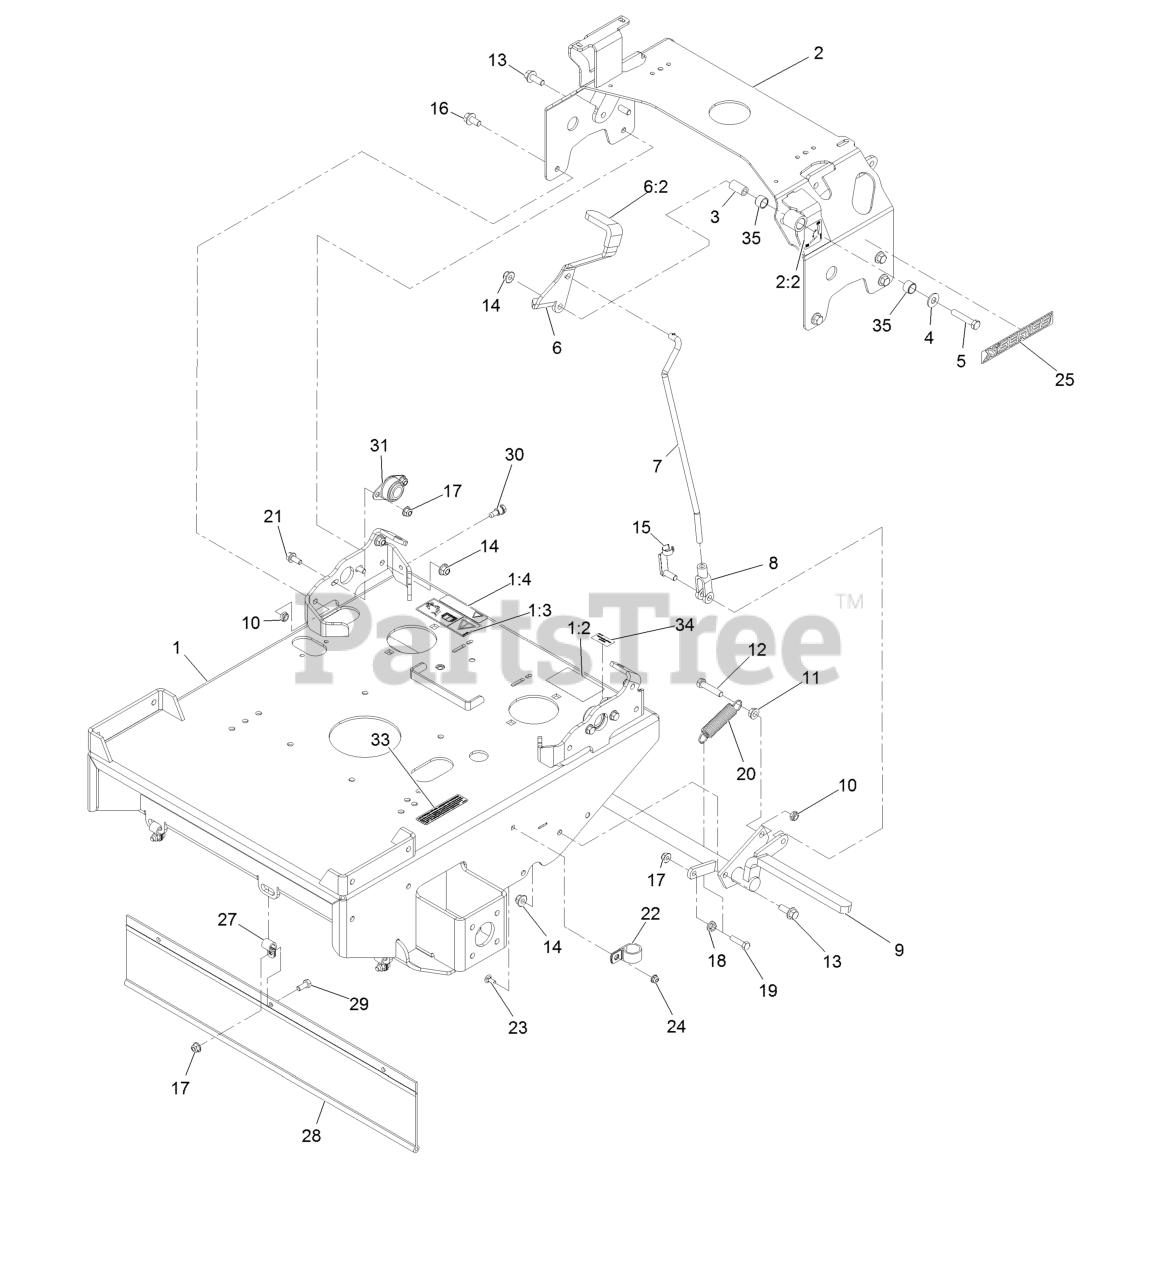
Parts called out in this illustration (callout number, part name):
1	ASM, Engine Deck W/ Decals
1:2	Decal-Warning
1:3	Decal-Warning, Sulky
1:4	Decal-Drive Release
2	ASM, Tank Support W/ Decal
2:2	Decal-Park Brake, CE
3	Bushing-Pivot
4	Washer-3/8 Std
5	Screw-HH 3/8-16 X 2
6	ASM, Brake Lever W/ Grip
6:2	Grip-Lever
7	Linkage-Brake
8	Yoke-Linkage, Brake
9	Wld,Brake Ttx
10	Nut-Nyloc 3/8-16 Thin
11	Nut-Whizlock 3/8-16
12	Screw-HH 3/8-16 X 1 3/4
13	Screw HHF 3/8-16 X 1
14	Nut-Nyloc 3/8-16 Flg
15	Pin-Clevis Spring 3/8
16	Screw-HH Flg 3/8-16 X 3/4
17	Nut-Nyloc 5/16-18 Flg
18	Nut-Whizlock 5/16-18
19	Screw-HH 5/16-18 X 1 1/4
21	Screw-HH Flg 5/16-18 X 3/4
22	Clip-Loom
23	Bolt-Carriage 1/4-20 X 5/8
24	Nut-Nyloc 1/4-20 Flg
25	Decal-X-Series
27	Clip-Loom
28	Shield, Drag
29	Screw-HH 5/16-18 X 3/4
30	Bolt-Shoulder
31	Bearing-Flanged
33	Decal-Arrester, Spark
34	Decal-Patent
35	Sleeve-Bushing
